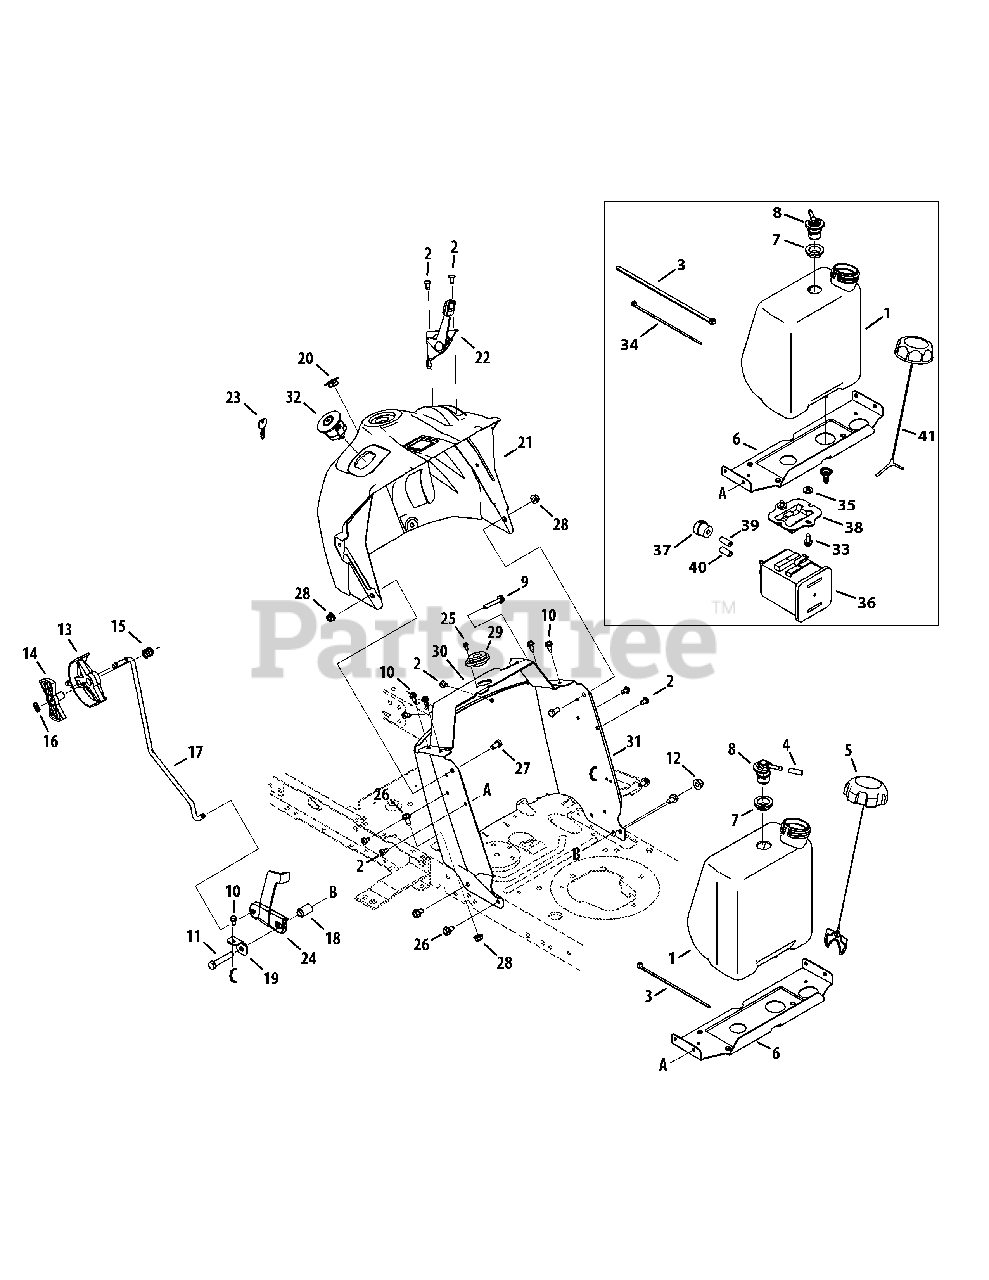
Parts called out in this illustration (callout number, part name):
1	Fuel Tank
2	Screw, Tap, 1/4-20x0.500
3	Cable Tie, 36.0 Long
4	Hose Vent
5	Fuel Cap, 2.25"
6	Gas Tank Support Bracket
7	Rubber Grommet, 23 x 3.55
8	Rollover Valve
9	Hex Screw, 1/4-20 x 1.50
10	Tap Screw, 1/4-20x 0.625
11	Hex Screw, 3/8-16x2.00, Gr5, Std
12	Flange Lock Nut, 3/8-16
13	Shift Lever
14	Index Control
15	Compr Spring, .685 OD x .63
16	Lock Washer, 1/4
17	Speed Selector Control Rod
18	Flange Spacer, .390 X .671 X 1.095
19	Speed Latch
20	Choke Plug
21	Dash, Upper
22	Throttle/Choke Cable Assembly
25	Screw, #10-16 x .500
26	Tap Screw,5/16-18, 0.625
27	Hex Screw, 5/16-18 x .625
28	Flange Lock Nut, 5/16-18
29	Bearing, .628 ID x 1.36
31	Dash, Lower
32	Key Switch
33	Screw, 5/16-18 x .750
34	Cable Tie
35	Flat Washer, .344 x .750 x .120
36	5 Gallon Carbon Canister
37	Vent Filter Canister
38	Canister Adaptor Bracket
39	Hose, Fuel, Low Perm, White
40	Hose, Fuel, Low Perm, Yellow
41	Fuel Cap, 2.25"
